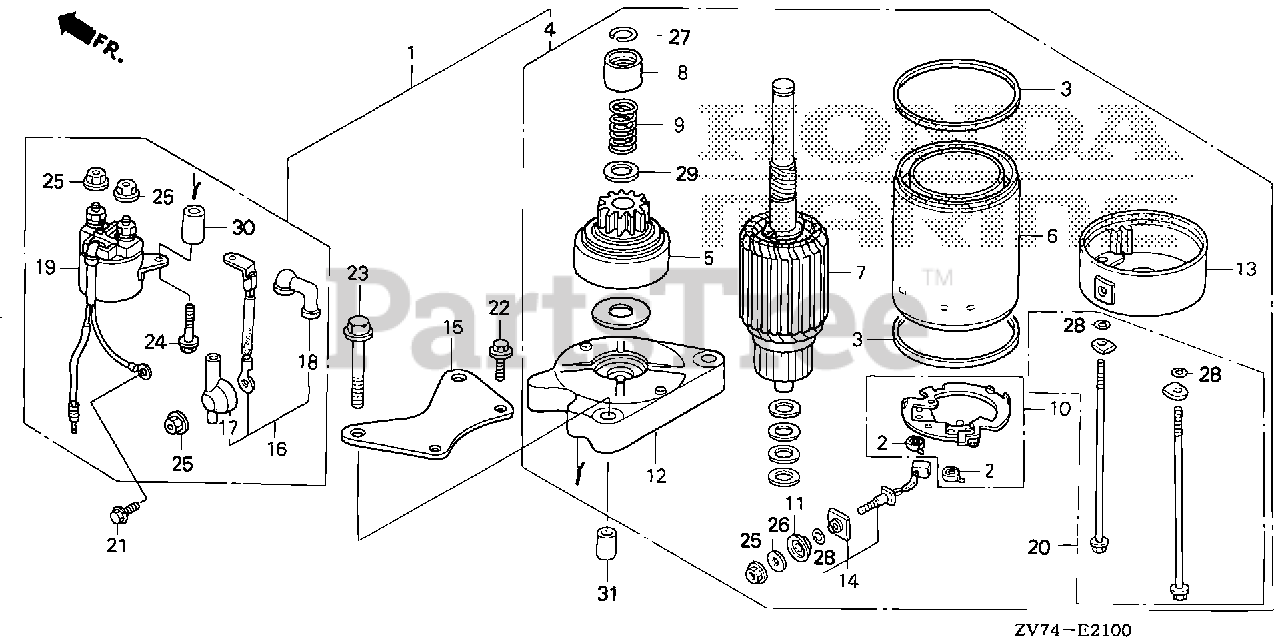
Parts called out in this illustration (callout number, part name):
1	STARTER MOTOR ASSY.
2	SPRING, CARBON BRUSH
4	STARTER MOTOR UNIT
8	PIECE, STOPPER
9	SPRING, RETURN
10	HOLDER, BRUSH
12	BRACKET, FR.
13	BRACKET, RR.
14	TERMINAL UNIT
15	STAY, STARTER MOTOR
16	WIRE, MAGNETIC SWITCH
17	COVER, STARTER TERMINAL
18	COVER, MAGNETIC SWITCH TERMINAL
19	SWITCH ASSY., STARTER MAGNETIC
20	BOLT SET, SETTING
21	BOLT, FLANGE (6X12) (CT200)
22	BOLT, FLANGE (6X16)
23	BOLT, FLANGE (8X45)
24	BOLT, FLANGE (6X25)
25	NUT-WASHER (6MM)
26	WASHER (6MM)
27	CIRCLIP (14MM)
28	O-RING (4X2)
30	COLLAR, DISTANCE
31	PIN, DOWEL (10X16)
